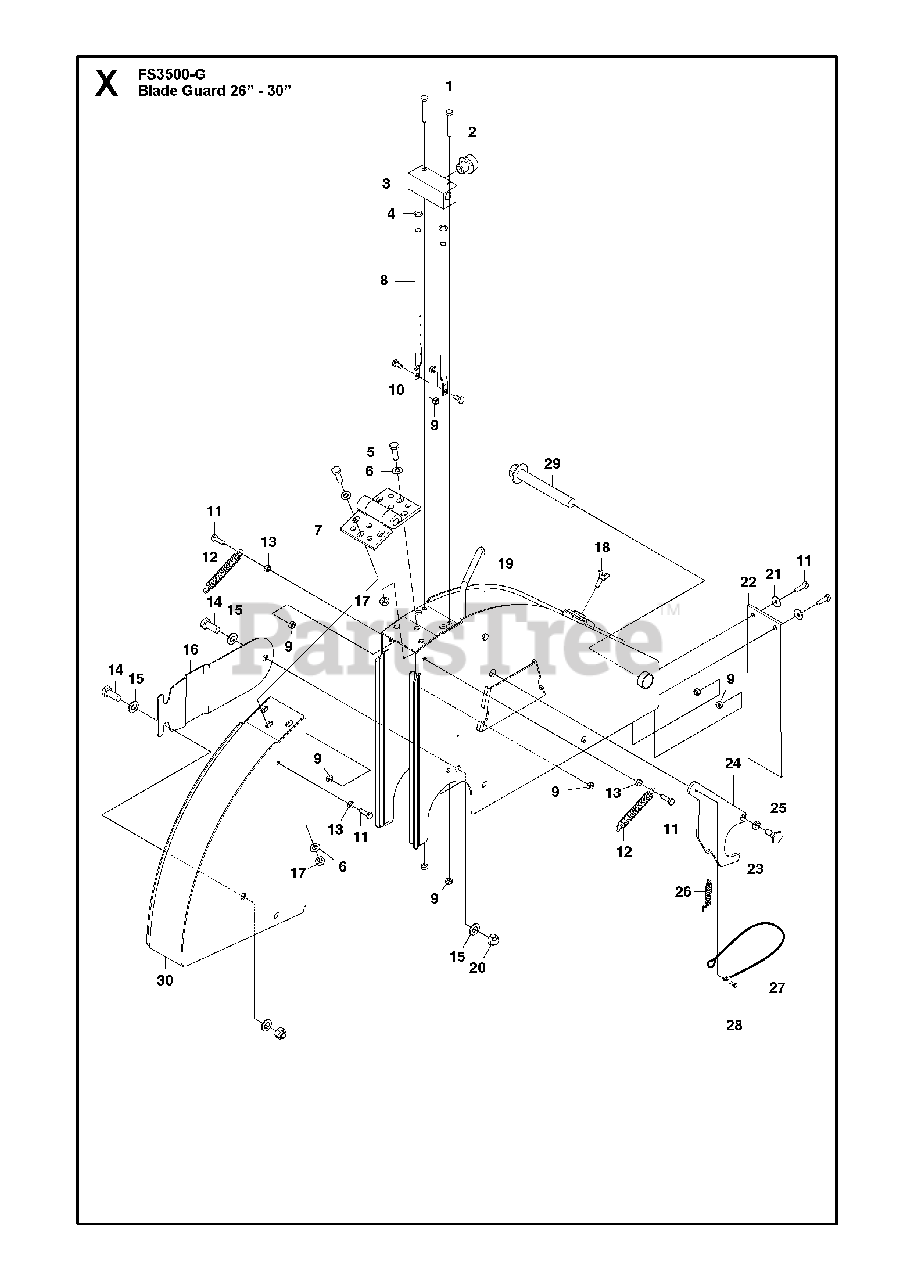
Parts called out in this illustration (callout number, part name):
6	WASHER
9	HEXAGON LOCKING NUT
15	WASHER
17	HEXAGON LOCKING NUT
20	HEXAGON LOCKING NUT
21	WASHER 1/4 SAE
